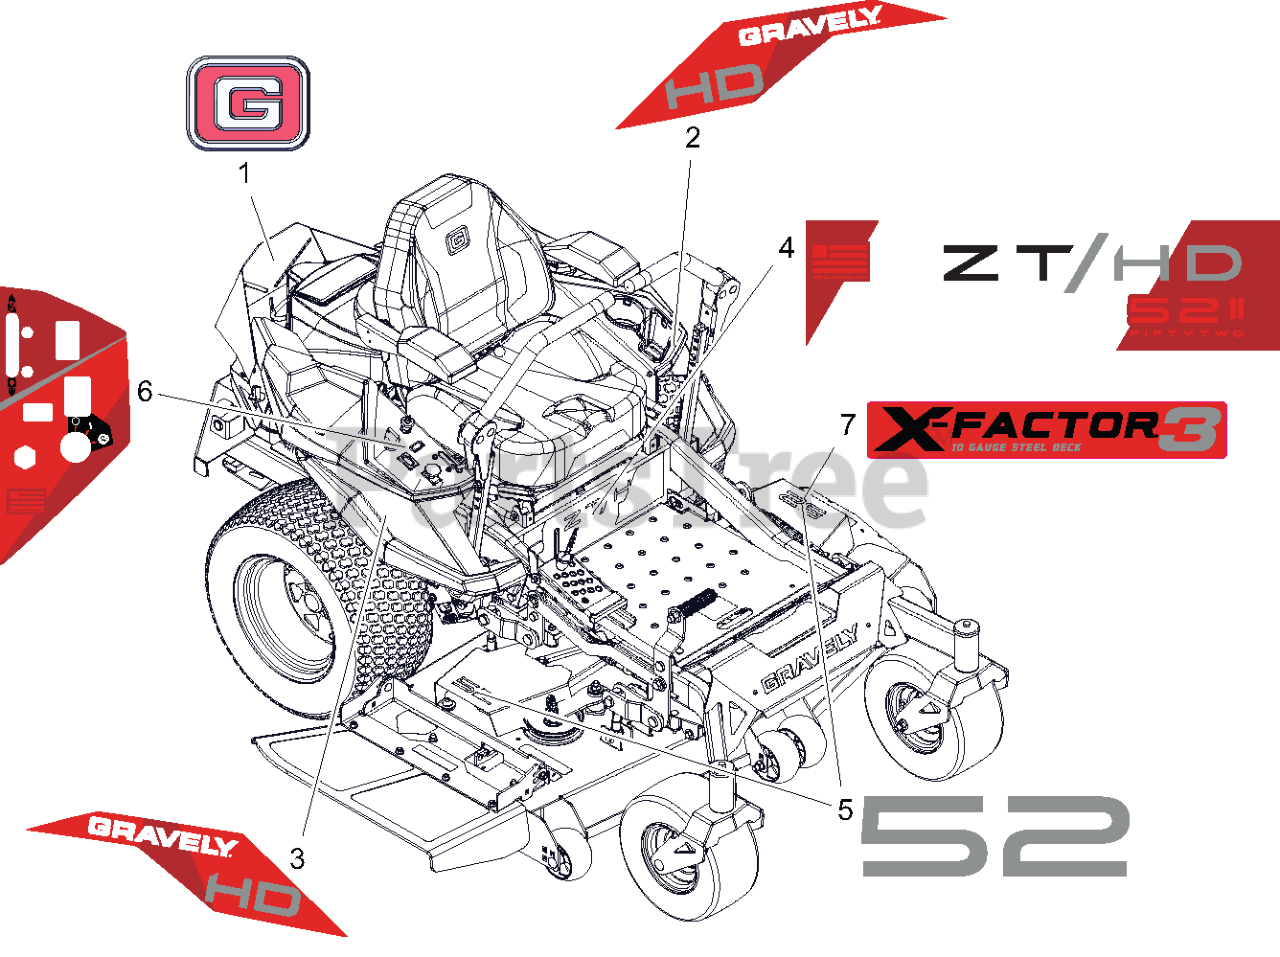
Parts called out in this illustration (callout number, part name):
1	DECAL, GRAVELY BRAND
2	DECAL, FENDER LH - HD
3	DECAL, FENDER RH - HD
4	DECAL, ZT/HD - 52
5	DECAL, DECK - 52
6	DECAL, CONTROL PANEL
7	DECAL, X-FACTOR 3
